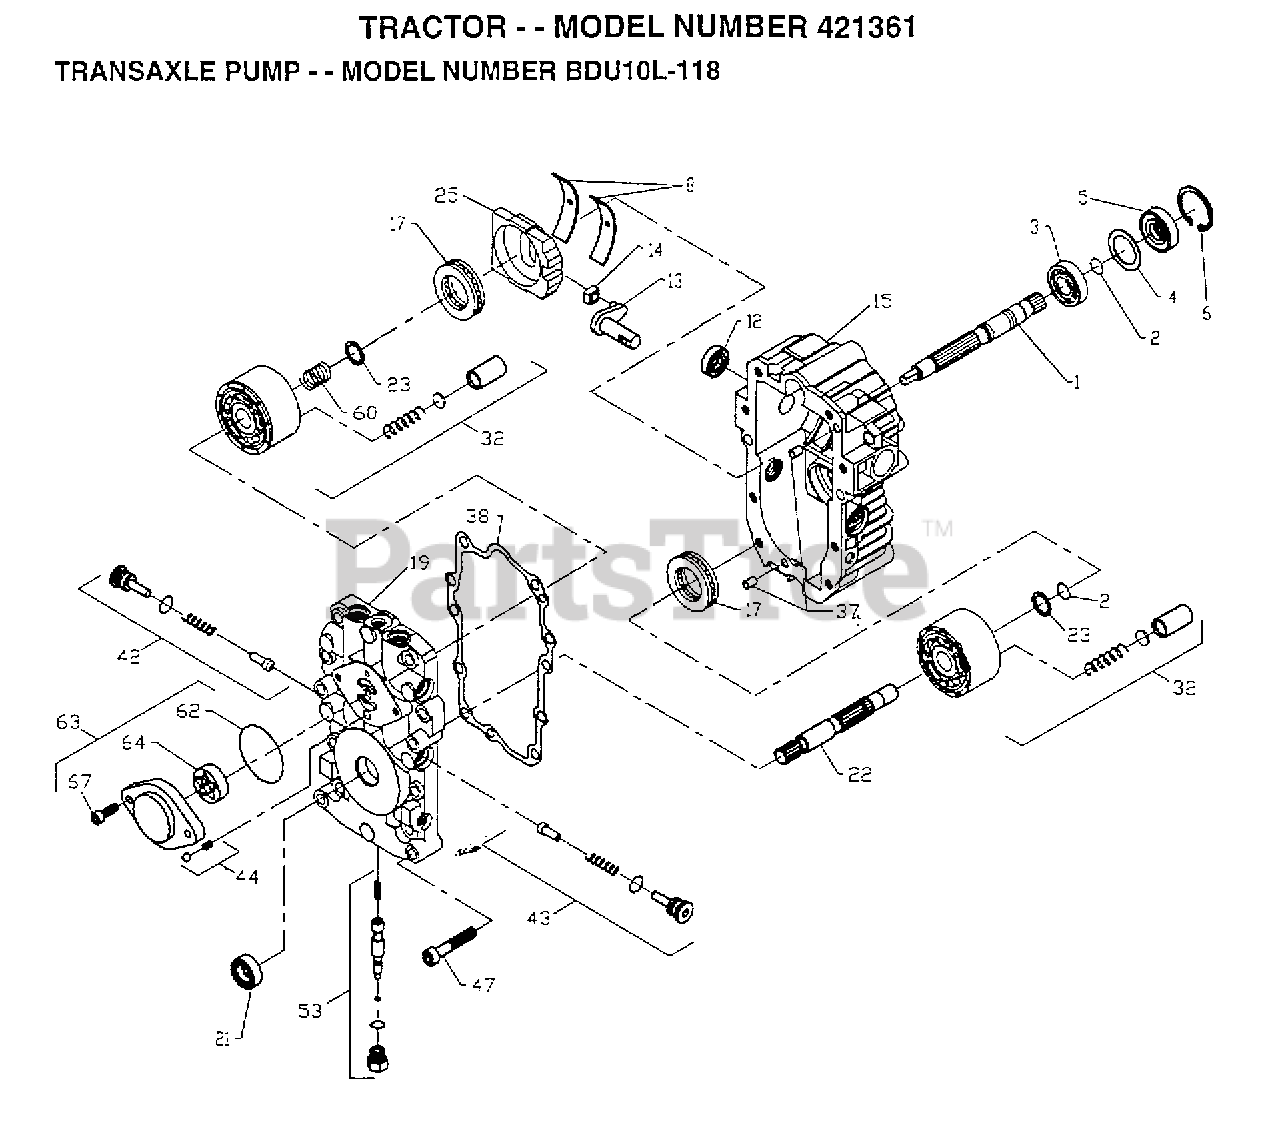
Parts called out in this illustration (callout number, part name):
1	SHAFT.PUMP.50158
2	RETAINIANG RING-(2003016)
3	BALL BEARING
4	SPACER
5	SEAL LIP
6	RING.RET.2003052
8	CRADLE BEARING (2003023)
12	SEAL.9008000-0126
13	TRUNION ARM (2003005)
14	GUIDE.2000015.HYD
15	KIT.HSG.2513035.
19	KIT.CENT.2513006
21	LIP SEAL-9008000-0127
22	SHAFT.MOT.2003034
23	WASHER.2003017
25	"SWASHPLATE,VARIAB"
32	BLOCK.CLYN.70079.
37	PIN
38	GASKET.20030600
42	KIT.VALVE.2510050
43	KIT.VALVE.2510050
44	KIT.RELI.2510011.
47	SCREW9007314-0808
53	"KIT,BYPASS VALVE"
60	SPRING.2003014.
62	0RING.90041011340
63	GEROTOR.J1041008
64	GEROTOR.J1041008
67	SCREW.CAP.50095.
